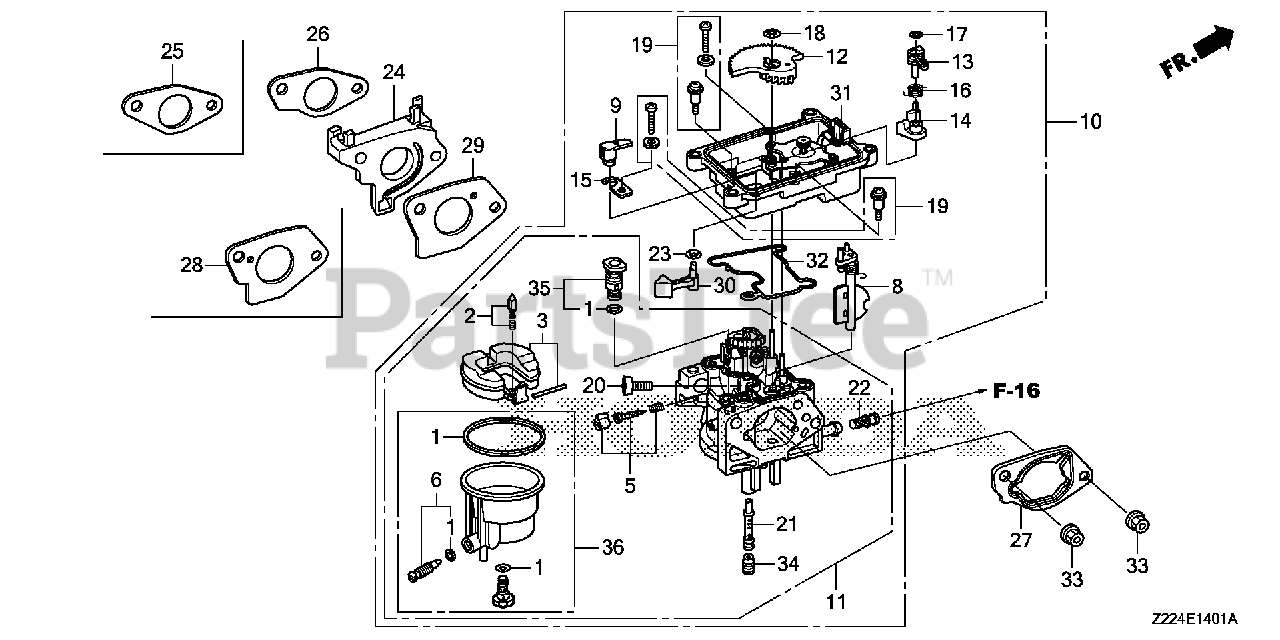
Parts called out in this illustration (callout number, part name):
1	GASKET SET
2	VALVE SET, FLOAT
3	FLOAT SET (CARBURETOR NO.)
5	SCREW SET (Honda Code 4219879). (CARBURETOR NO.)
6	SCREW SET, DRAIN (ADVENTURE GREEN) (CARBURETOR NO.)
9	ARM, MANUAL START
10	CARBURETOR ASSY. (BE96A D)
11	CARBURETOR SET
12	GEAR, MIDDLE
13	ARM, CHOKE
14	LEVER, CHOKE CONTROL
16	SPRING, TORSION COIL
17	CLIP, SPECIAL
18	CLIP, SPECIAL
20	SCREW, STOP
21	NOZZLE, MAIN
22	SCREEN, FUEL STRAINER
23	O-RING (CARBURETOR NO.)
24	INSULATOR, CARBURETOR
26	GASKET, CARBURETOR INSULATOR
27	SPACER, CARBURETOR
29	GASKET, CARBURETOR
30	LEVER, MANUAL START
31	CASE, MOTOR
33	NUT, FLANGE (6MM)
34	JET, MAIN (#105) Use from Engine SN BE87H A.
34	JET, MAIN (#108) (CARBURETOR NO.)
34	JET, MAIN (#112)
35	JET SET, PILOT (#45) (CARBURETOR NO.)
36	BOLT KIT, FUEL CHAMBER
